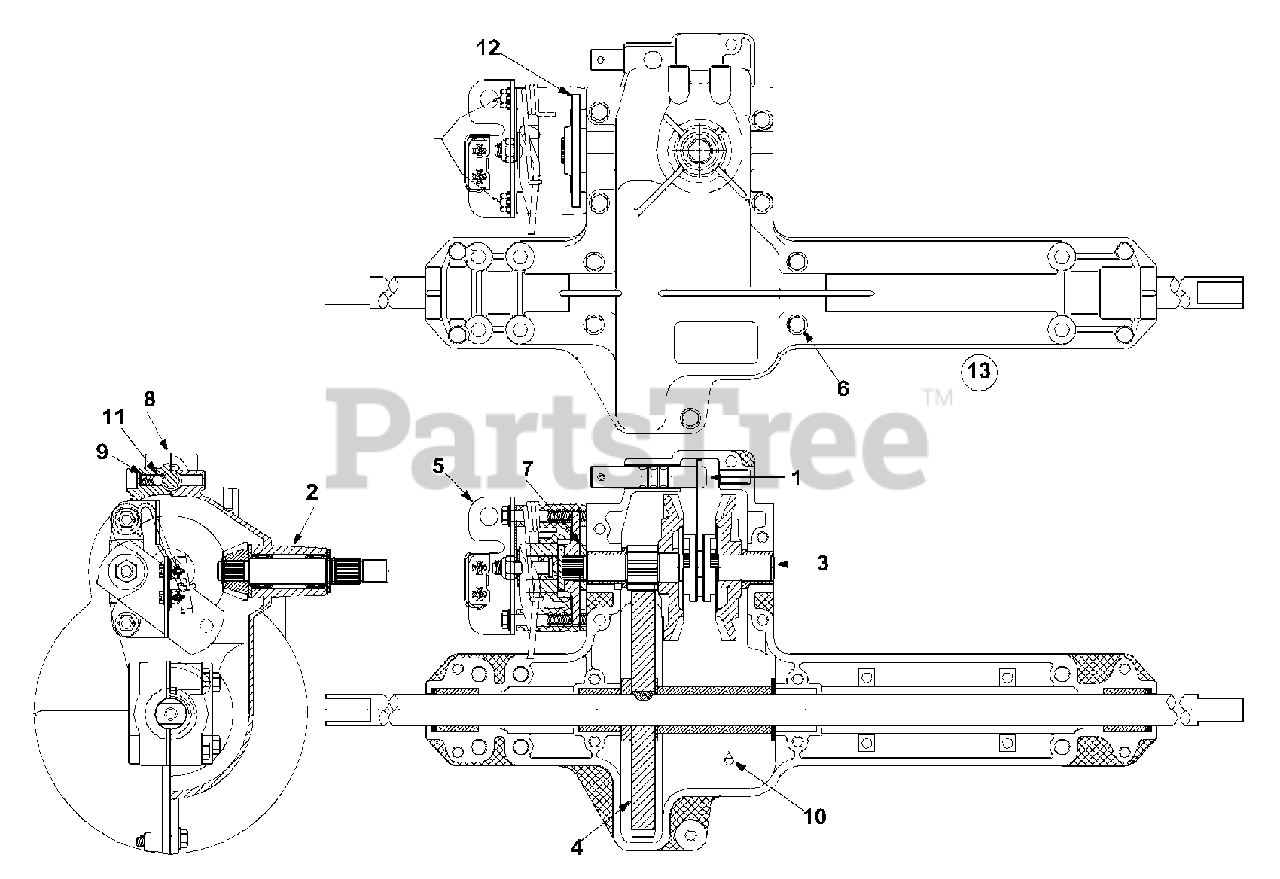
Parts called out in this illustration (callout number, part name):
1	Shaft Assembly: Detent
2	Upper Housing Assembly
3	Drive Shaft Assembly: LH Brake
4	Axle Assembly
5	Brake Assembly: Yoke LH
6	TT Screw 1/4-20 x 1.625"
7	Break Pad
8	Lower Housing
9	Spring Detent
10	Grease
11	Ball: Detent: .250
12	Brake Disc
13	Transmission Assembly Complete: Single Speed
